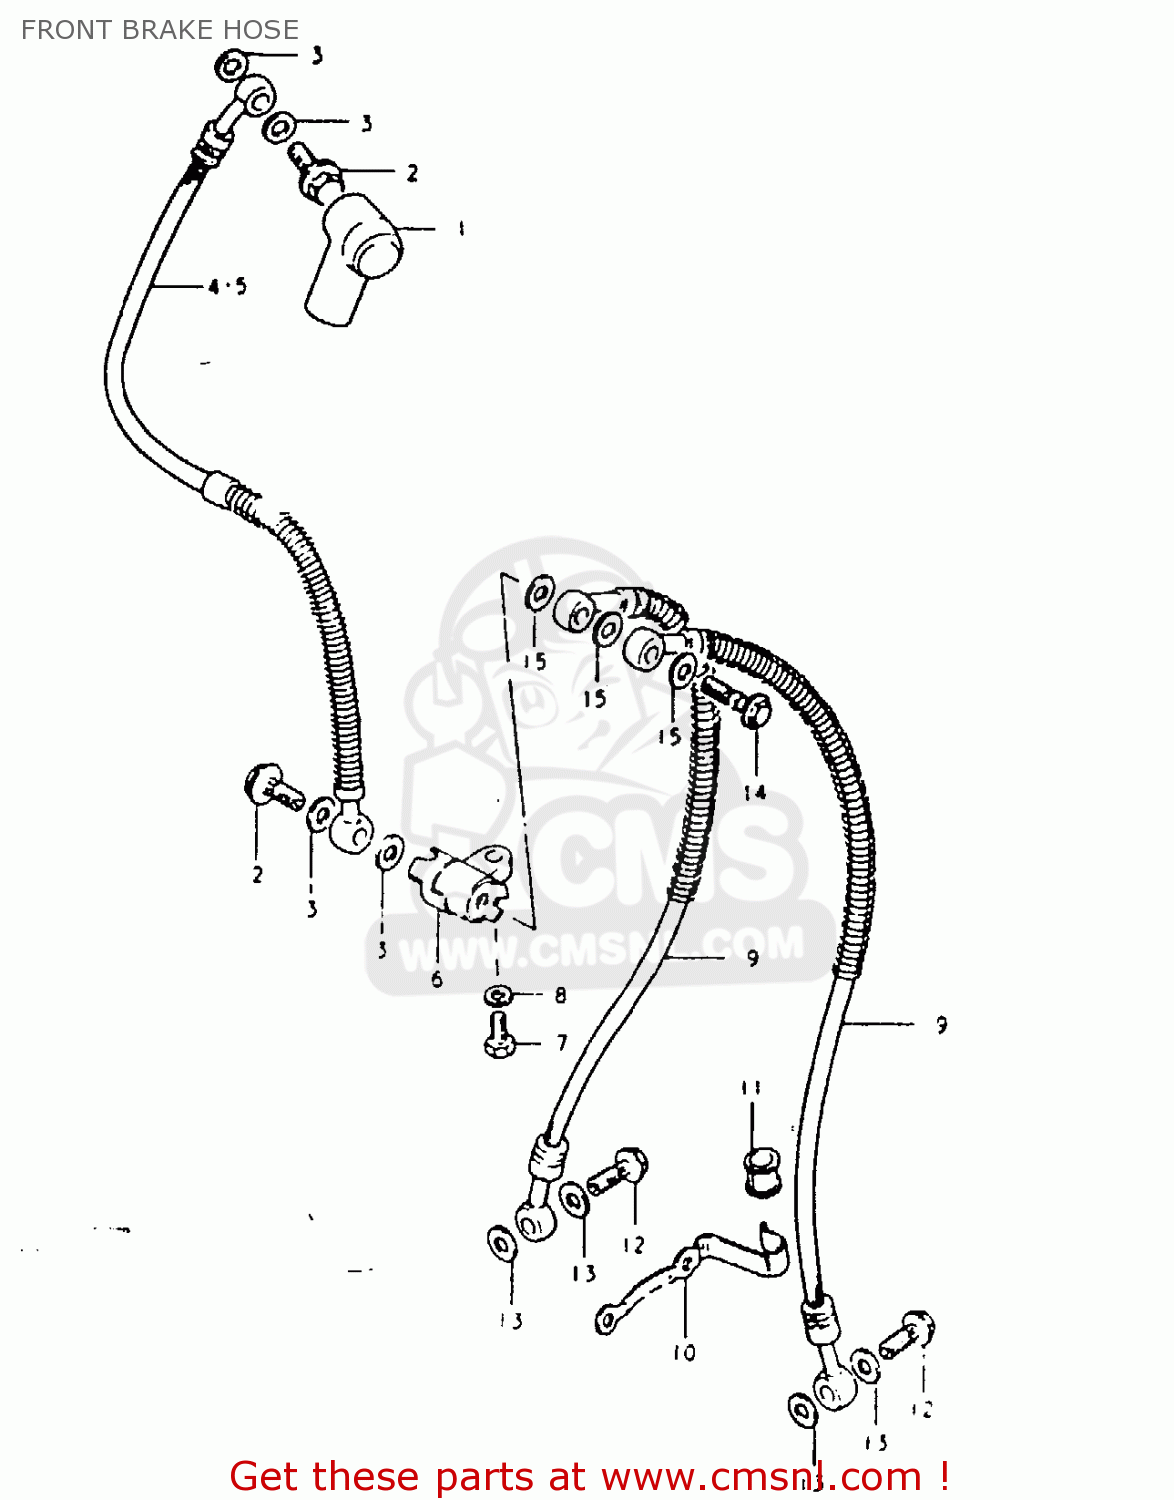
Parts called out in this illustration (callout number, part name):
1	BOOT,MASTER CYLINDER
2	BOLT,UNION
3	WASHER
4	HOSE,FRONT BRAKE
5	HOSE,FRONT BRAKE
6	JOINT,BRAKE HOSE
7	BOLT
8	LOCK WASHER
9	HOSE, BRAKE NO.2
10	GUIDE,BRAKE HOSE NO.2
11	BUSH,BRAKE HOSE GUIDE,NO.2
12	BOLT,UNION
13	WASHER
14	BOLT,UNION
15	WASHER
